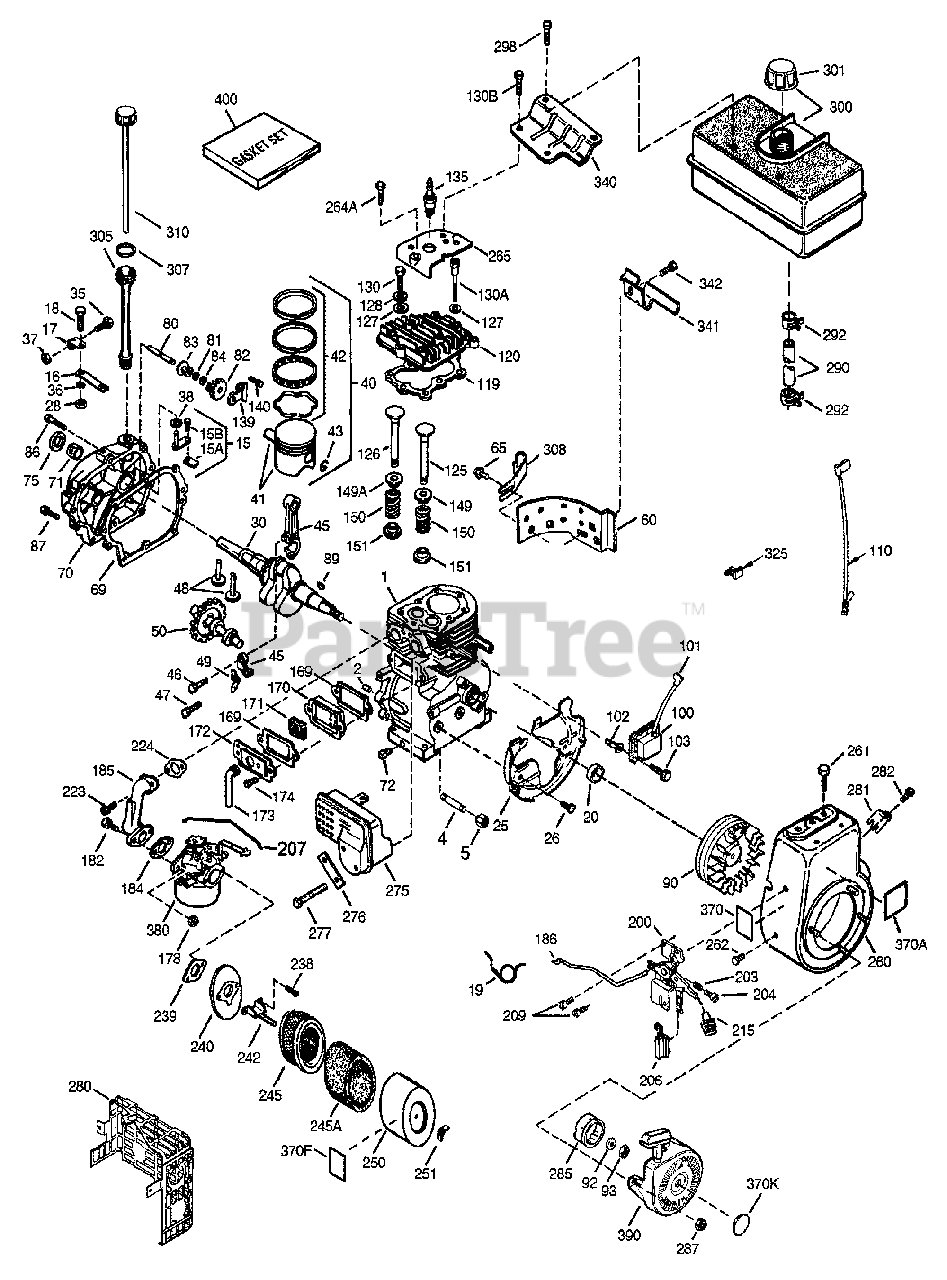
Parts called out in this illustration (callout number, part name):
1	Cylinder
2	Dowel Pin
4	Oil Drain Extension
5	Extension Cap
15	Governor Rod
15A	Governor Yoke
15B	Screw, 6-40 x 5/16"
16	Governor Lever
17	Governor Lever Clamp
18	Screw, 8-32 x 5/16"
19	Speed Control Spring
25	Blower Housing Baffle
26	Screw, 1/4-20 x 5/8"
28	Lock Nut, 3-32
30	Crankshaft
35	Screw, 10-32 x 3/4"
36	Lock Washer
37	Lock Nut, 10-32
38	Retaining Ring
40	Piston, Pin & Ring Set (Standard)
41	Piston & Pin Ass'y (Standard)
42	Ring Set (Standard)
43	Piston Pin Retaining Ring
45	Connecting Rod Ass'y
46	Connecting Rod Bolt
47	Connecting Rod Bolt
48	Valve Lifter
49	Oil Dipper
50	Camshaft (MCR)
60	Blower Housing Extension
65	Screw, 10-24 x 1/2"
69	Cylinder Cover Gasket
70	Cylinder Cover
71	Crankshaft Bushing
72	Oil Drain Plug
80	Governor Shaft
82	Governor Gear Ass'y
83	Governor Spool
84	Retaining Ring
86	Screw, 1/4-20 x 1-1/4"
87	Screw, 1/4-20 x 1-11/16"
89	Flywheel Key
92	Lock Washer
93	Flywheel Nut
100	Solid State Ignition
101	Spark Plug Cover
102	Solid State Mounting Stud
103	Screw, Torx T-15, 10-24 x 15/16"
110	Ground Wire
119	Cylinder Head Gasket
120	Cylinder Head
125	Exhaust Valve (Standard)
126	Intake Valve (Standard)
128	Bell Washer
130	Screw, 5/16-18 x 1-1/2"
130A	Screw, 5/16-18 x 1-3/4"
130B	Screw, 1/4-20 x 5/8"
135	Resistor Spark Plug (J8C/356)
139	Governor Gear Bracket
140	Screw, 10-24 x 1/2"
149	Valve Spring Cap
149A	Valve Spring Cap
150	Valve Spring
151	Valve Spring Keeper
169	Valve Cover Gasket
170	Breather Body
171	Breather Element
172	Valve Cover
173	Breather Tube
174	Screw, 10-24 x 1/2"
178	Nut and Lock Washer, 1/4-28
182	Screw, 1/4-20 x 1"
184	Carb. to Intake Pipe Gasket
185	Intake Pipe
186	Governor Link
200	Control Bracket
203	Compression Spring
204	Screw, 5-40 x 7/16"
207	Throttle Link
209	Screw, 10-32 x 1/2"
215	Control Knob
223	Screw, Torx T-30, 5/16 -18 x 1-1/8"
224	Intake Pipe Gasket
238	Screw, 10-32 x 1/2"
239	Air Cleaner Gasket
240	Air Cleaner Body
242	Air Cleaner Bracket
251	Wing Nut, 1/4-20
264A	Screw, 1/4-20 x 5/8"
281	Starter Bubble Cover
290	Fuel Line
305	Oil Fill Tube
341	Fuel Tank Bracket
370K	Starter Decal
400	Gasket Set
